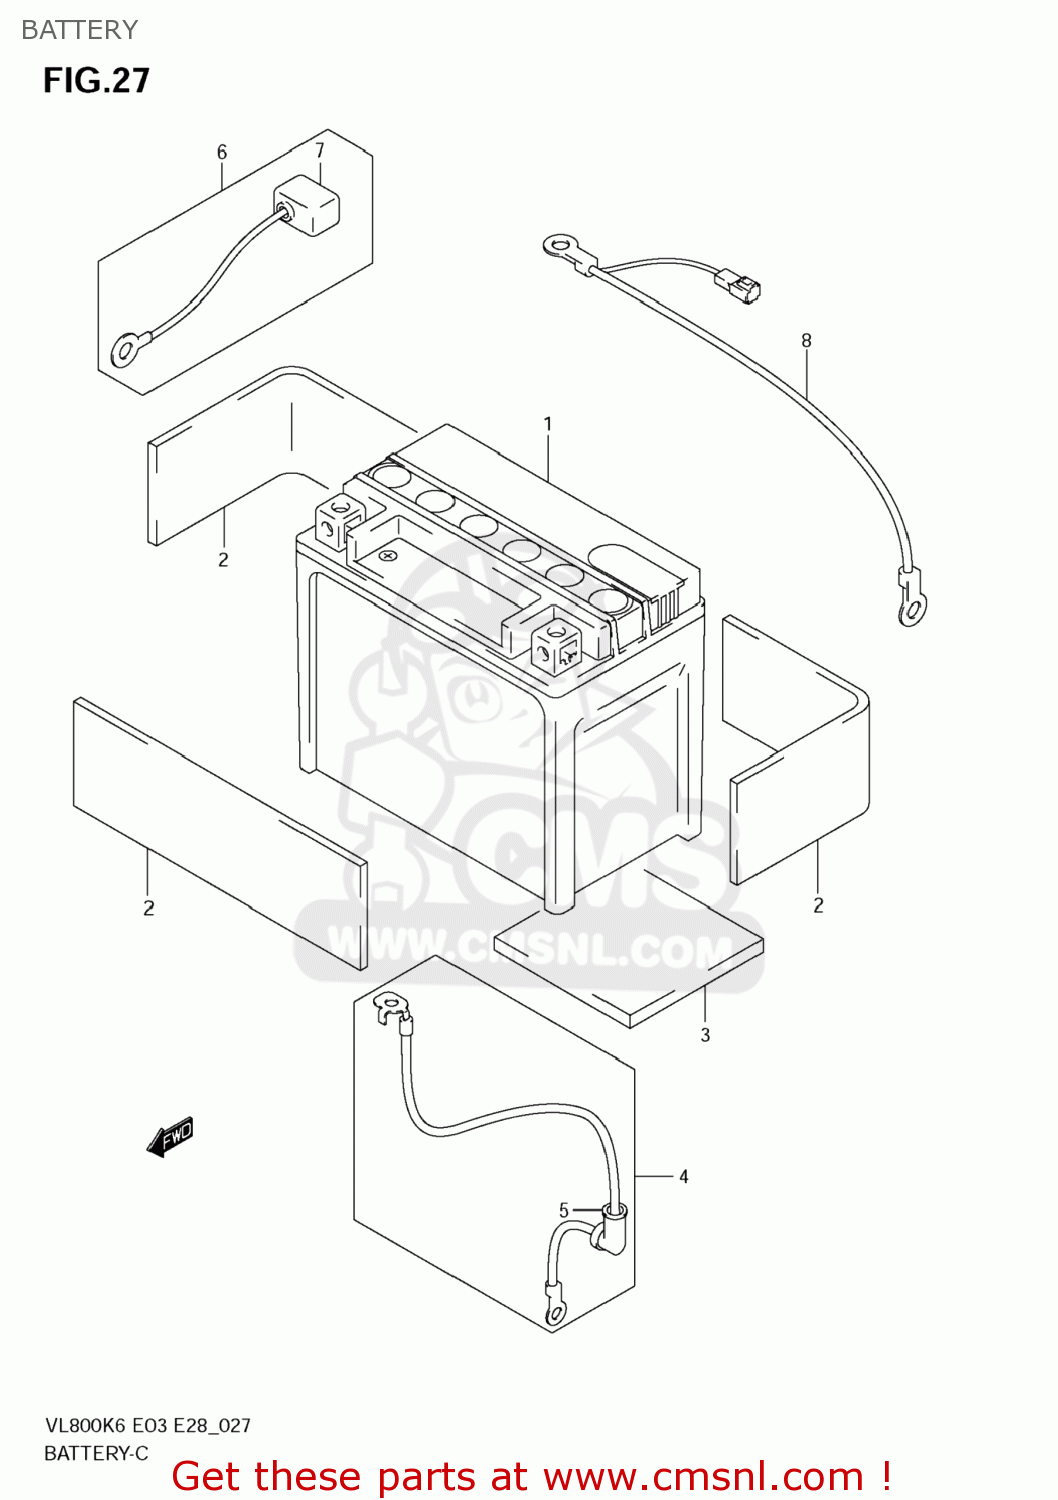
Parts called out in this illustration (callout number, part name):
1	BATTERY ASSEMBLY (12V) FTX
2	PROTECTOR(170X95X3.0)
3	PROTECTOR(50X50X5)
4	WIRE,STARTER MOTOR LEAD
5	CAP,STARTER MOTOR LEAD
6	WIRE,BATTERY PLUS LEAD
7	CAP,BATTERY PLUS
8	WIRE,BATTERY MINUS
